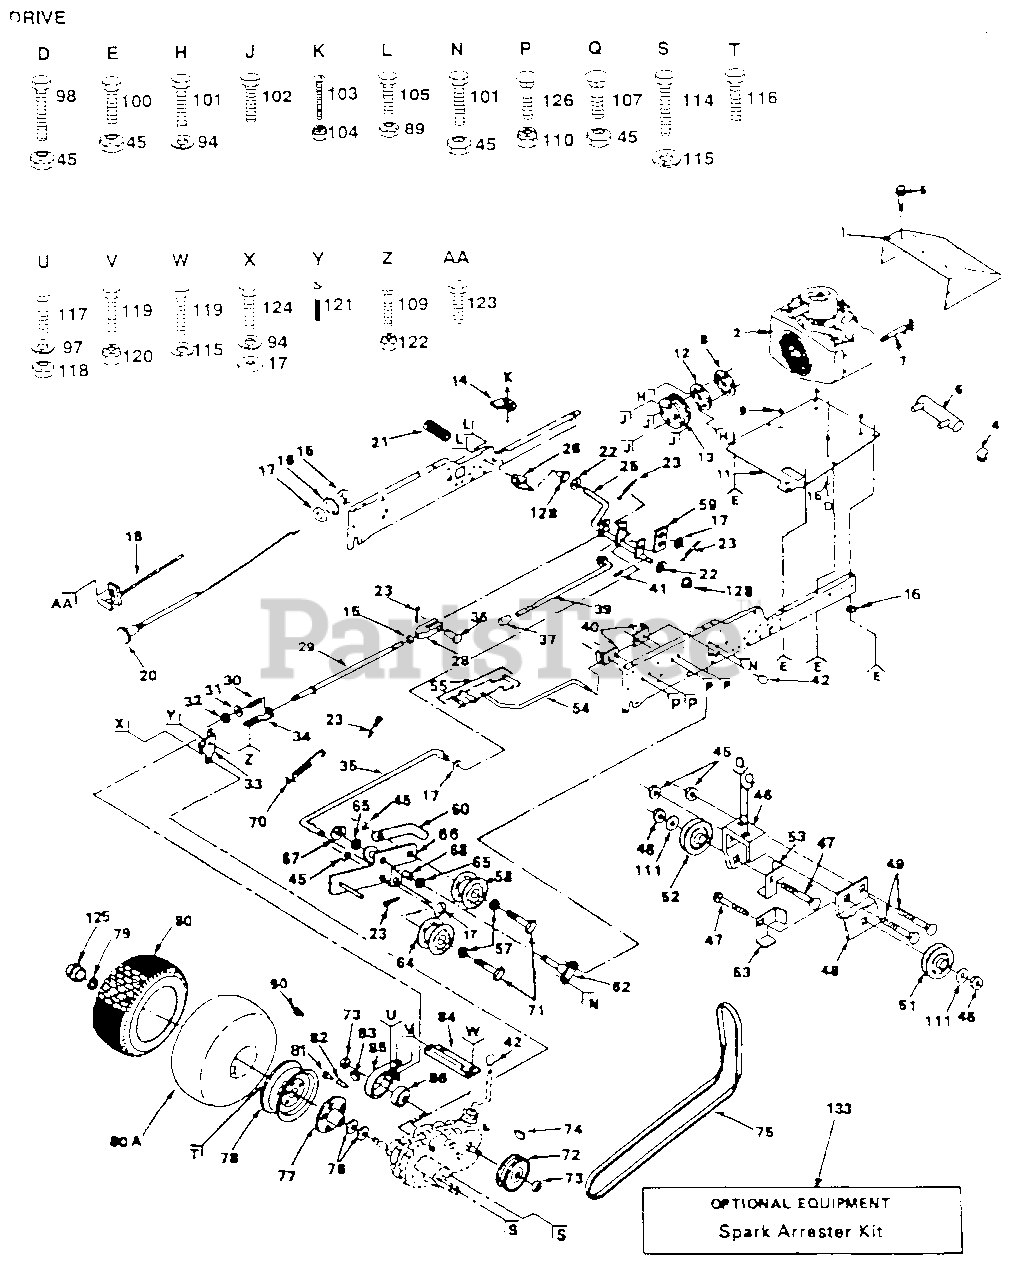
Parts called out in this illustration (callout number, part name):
2	Engine, 18 HP, Kohler, Model #M18S-24639
4	Pipe, Exhaust
5	Screw, Hex Thd. Cut. 1/4-20 x 1/2
6	Muffler, Exhaust
7	Valve, Oil Drain
13	Pulley, Ground Drive
14	Actuator, Switch, Interlock
15	Nut, Hex 3/8-24
16	Washer, Lock Ext. Tooth 3/8
17	Washer 13/32 x 13/16 x 16 Ga.
18	Control, Throttle
20	Control, Choke
21	Cover, Pedal
22	Washer 25/32 x 1-1/4 x 16 Ga.
23	Pin, Cotter 3/32 x 3/4
25	Shaft, Foot Pedal
26	Bracket, Interlock
30	Spring, Compression
31	Washer 13/32 x 1 x 14 Ga.
32	Locknut 3/8-24
33	Bracket, Brake
34	Guide, Rod, Brake
39	Rod, Parking Brake
40	Bracket, Rod, Shift
41	Pin, Roll 3/16 x 1-1/4
42	Knob
45	Locknut 3/8-16
46	Bracket, V-Pulley, Drive, Mule
47	Bolt, Carriage 3/8-16 x 1-3/4
48	Bracket, Idler, Flat
49	Bolt, Carriage 3/8-16 x 3/4
52	Pulley, Idler
54	Rod, Shift, Hi - Lo
55	Connecting Link, Spring Clip
57	Washer 13/32 x 7/8 x 13 Ga.
58	Idler, Flat
59	Retainer, Spring
60	Retainer, Belt
62	Bracket Assembly, Clutch
64	Idler, Grooved
65	Washer, Hardened
66	Bracket, Clutch w/Bearing (Incl. Key No. 68)
68	Bearing, Idler
70	Spring, Extension
71	Bolt, Hex 3/8-16 x 1-3/4
72	Pulley, Transaxle
73	Locknut 1/2-20
74	Key, Woodruff 3/16 x 5/8
76	Washer, Thrust, Axle
77	Bushing Assembly and Wheel Hub
78	Rim Assembly, Rear
80	Tire, Rear
83	Key, Woodruff #9 (3/16 x 3/4)
84	Bracket, Support, Transaxle
89	Nut, Crownlock 1/4-20
90	Fitting, Grease
94	Washer, Lock 3/8
97	Washer, Lock 1/4
98	Bolt, Hex 3/8-16 x 1-1/4 Gr. 5
100	Bolt, Hex 3/8-16 x 3/4
101	Bolt, Hex 3/8-16 x 1 Gr. 5
102	Screw, Hex 5/16-18 x 1
103	Screw, Fin #10-24 x 1
104	Locknut #10-24
105	Bolt, Hex 1/4-20 x 3/4
107	Bolt, Carriage 3/8-16 x 3/4 Gr. 5
109	Bolt, Carriage 5/16-18 x 3/4
110	Locknut 5/16-18
111	Washer 13/32 x 1 x 12 Ga.
114	Bolt, Hex 7/16-14 x 1-1/4
115	Washer, Lock 7/16
116	Bolt, Hub
117	Bolt, Carriage 1/4-20 x 5/8
118	Nut, Hex 1/4-20
119	Bolt, Hex 7/16-14 x 1
120	Nut, Crownlock 7/16-14
121	Screw, Mach. Udrcut. Flat Head, 3/8-16 x 3/4
122	Locknut 5/16-18
123	Screw, Hex 1/4-20 x 1/2
124	Bolt, Hex 3/8-16 x 7/8
125	Cap, Axle, Rear
126	Bolt, Carriage 5/16-18 x 3/4
128	Nyliner
133	Spark Arrester Kit
